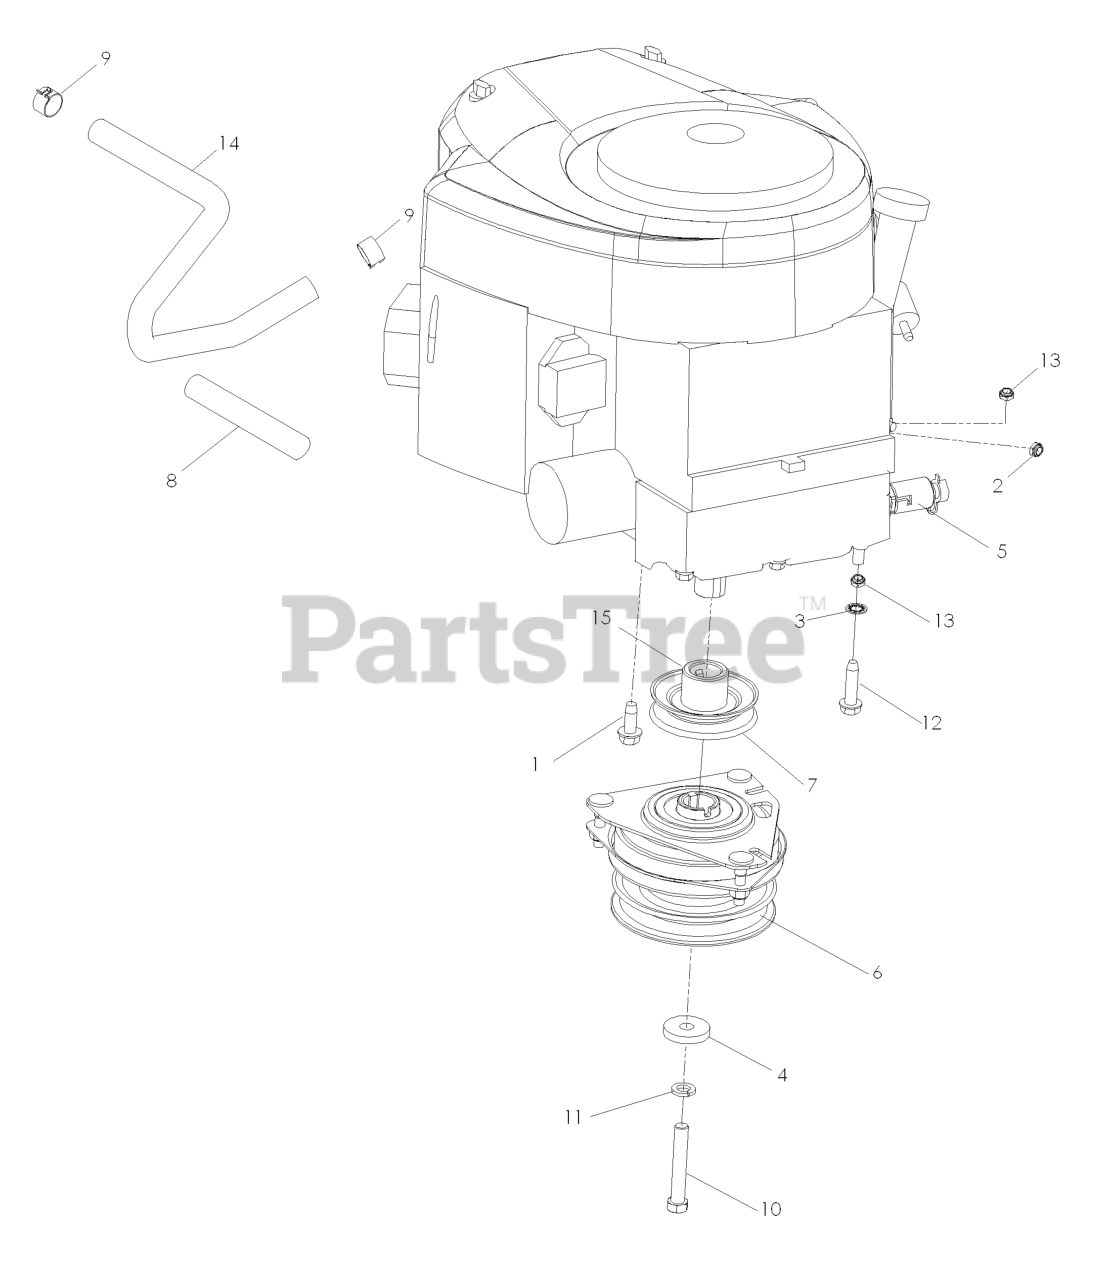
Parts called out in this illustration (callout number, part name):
1	BOLT 3/8-16 X 1.0
2	JAM NUT 1/4C (2 2 PW01)
3	WASHER, 3/8 ITLW ZN
4	CLUTCH, WASHER
5	OIL DRAIN FITTING
6	CLUTCH 90 FT/LB OGURA
7	PULLEY, ENGINE
8	FUEL LINE 5"
9	HOSE CLAMP
10	HEX SCREW 7/16-20 X 3
11	WASHER 7/16 LOCK
12	BOLT 3/8-16 X 1 1/2 ZINC CLEAR
13	NUT 3/8-16 NYLOC
14	FUEL LINE 13"
15	SPACER, ENGINE - PULLEY
